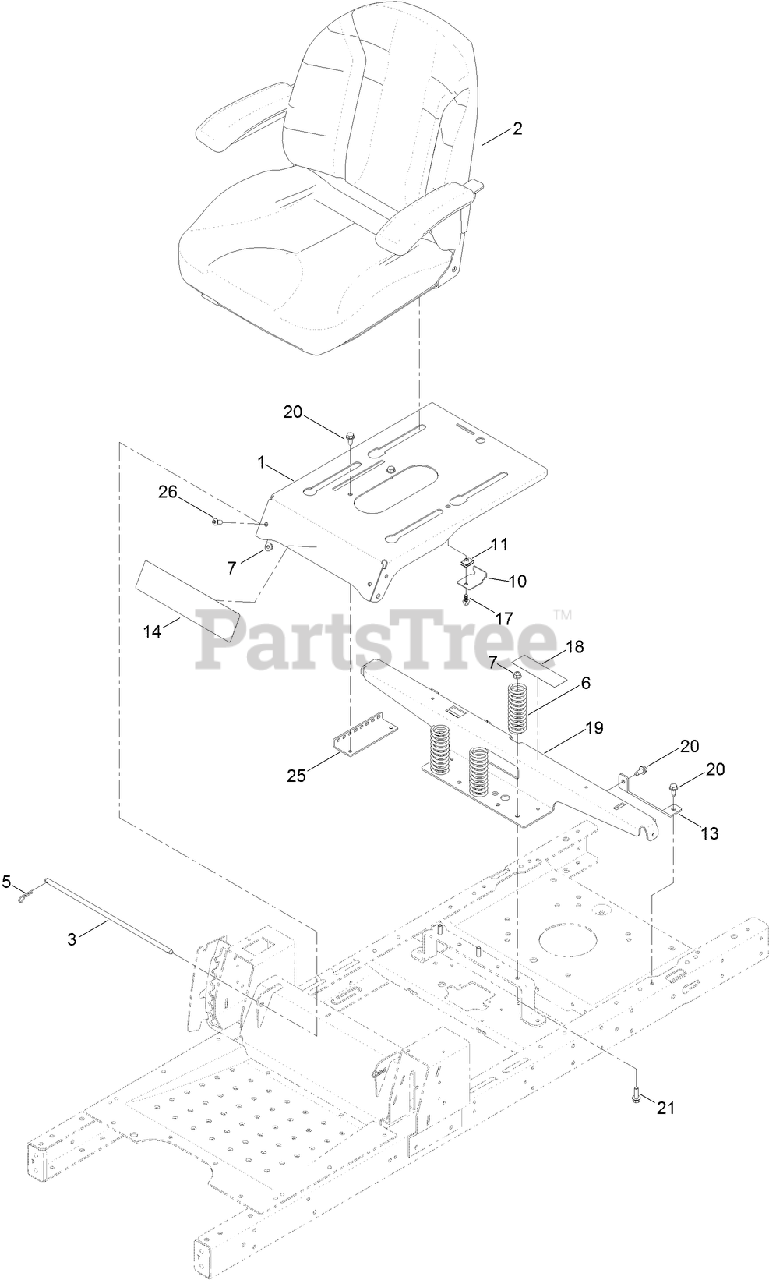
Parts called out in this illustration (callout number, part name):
2	SEAT ASM
3	ROD-PIVOT, NARROW
5	PIN-COTTER
6	SPRING-COMPRESSION
7	NUT-HF, NI
10	BRACKET-STOP, SEAT
13	SUPPORT-TANK, REAR
14	DECAL-TIMECUTTER
17	SCREW-HHF
18	DECAL-SERVICE, CE
19	SUPPORT-POD
20	SCREW-HWHTF
21	SCREW-HHF
25	BRACKET-LATCH, SEAT
26	SCREW-HSBH
